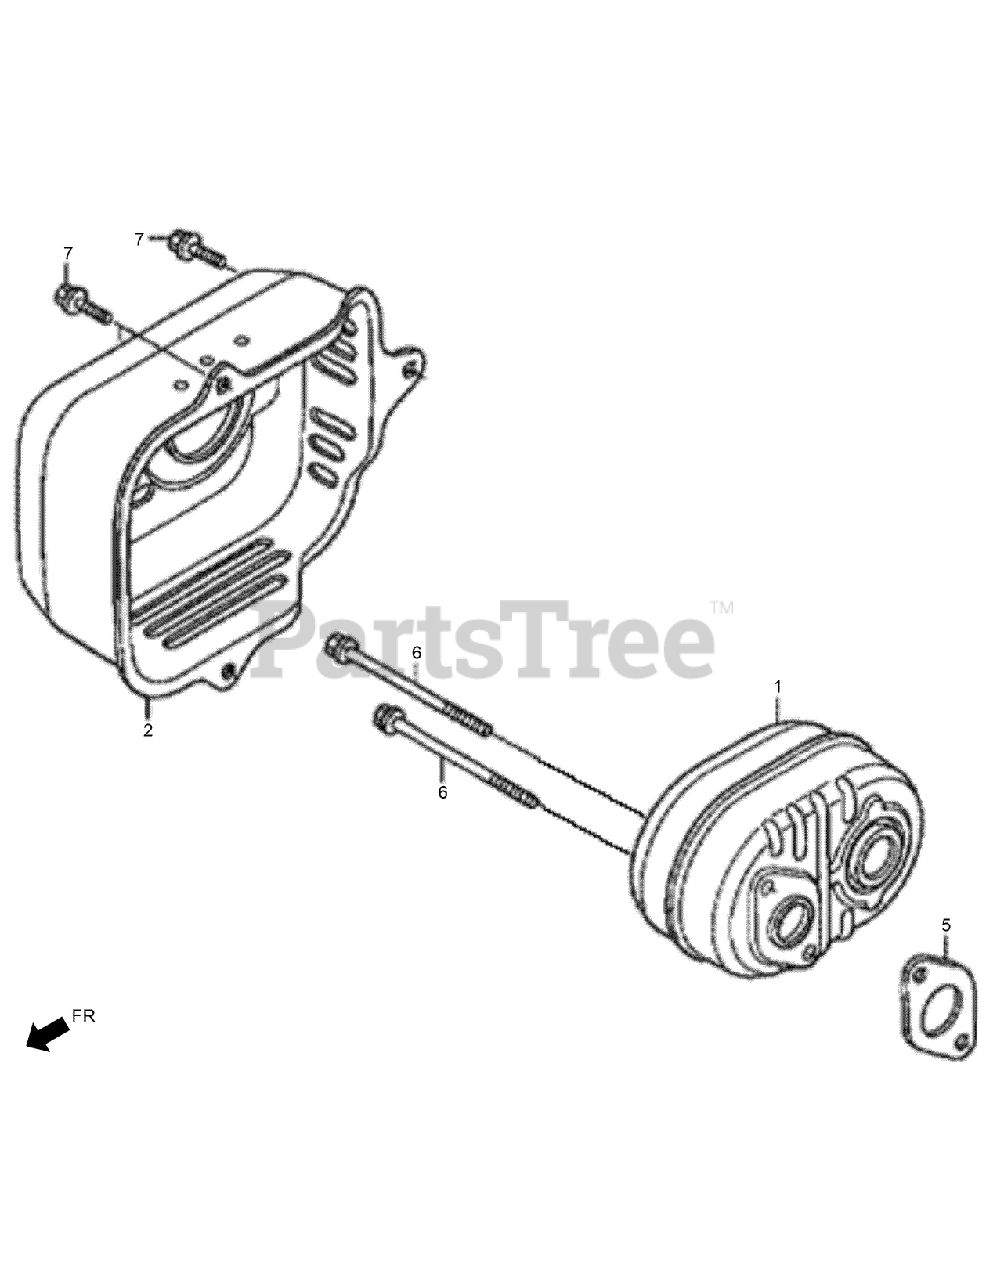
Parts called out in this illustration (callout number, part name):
2	MUFFLER PROTECTOR ASM
2	PROTECTOR-MUFFLER
5	GASKET-MUFFLER
6	BOLT-FLANGE-6X79
7	BOLT-FLANGE-6X12
